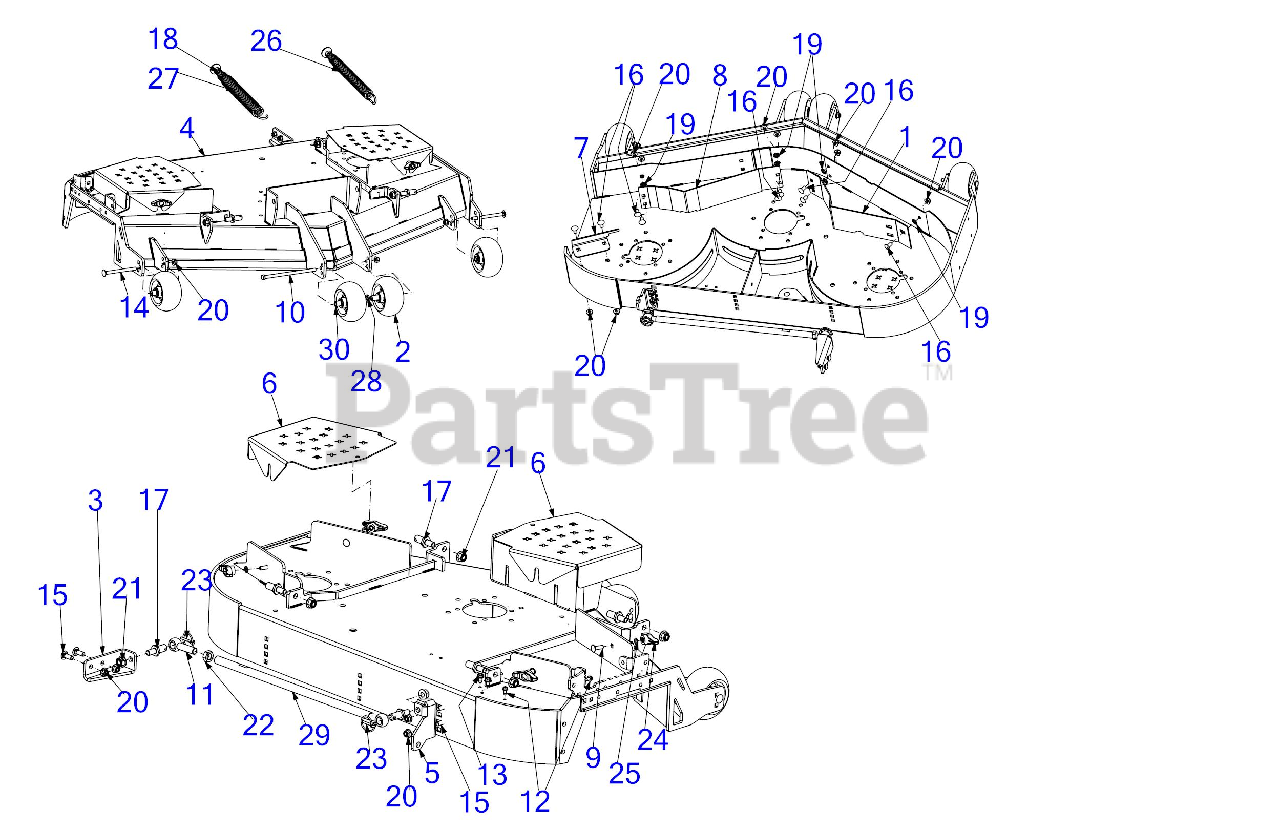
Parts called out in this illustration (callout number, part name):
2	5" DIA DECK WHEEL COMPLETE
9	CARRIAGE BOLT 5/16-18 x 1.00
10	SCREW 3/8-16 x 7.25 GR5
11	BOLT 5/8-16 x 2.63
12	SCREW 1/4-20 X.500
13	SCREW 5/16-18 x .500
14	CARRIAGE BOLT 3/8-16 x 4.25 GR5
15	CARRIAGE BOLT 3/8-16 x 1.00 GR5
16	CARRIAGE BOLT 3/8-16 x .75
18	SPRING INSERT SCREW
22	HEX NUT
24	WING KNOB 5/16-18
26	EXTENTION SPRING 1.20 x 11.35
27	EXTENSION SPRING 1.44 OD X 11.36
28	FLAT WASHER .632X1.00X.16
30	WHEEL SPACER .38ID x 3.04LG
